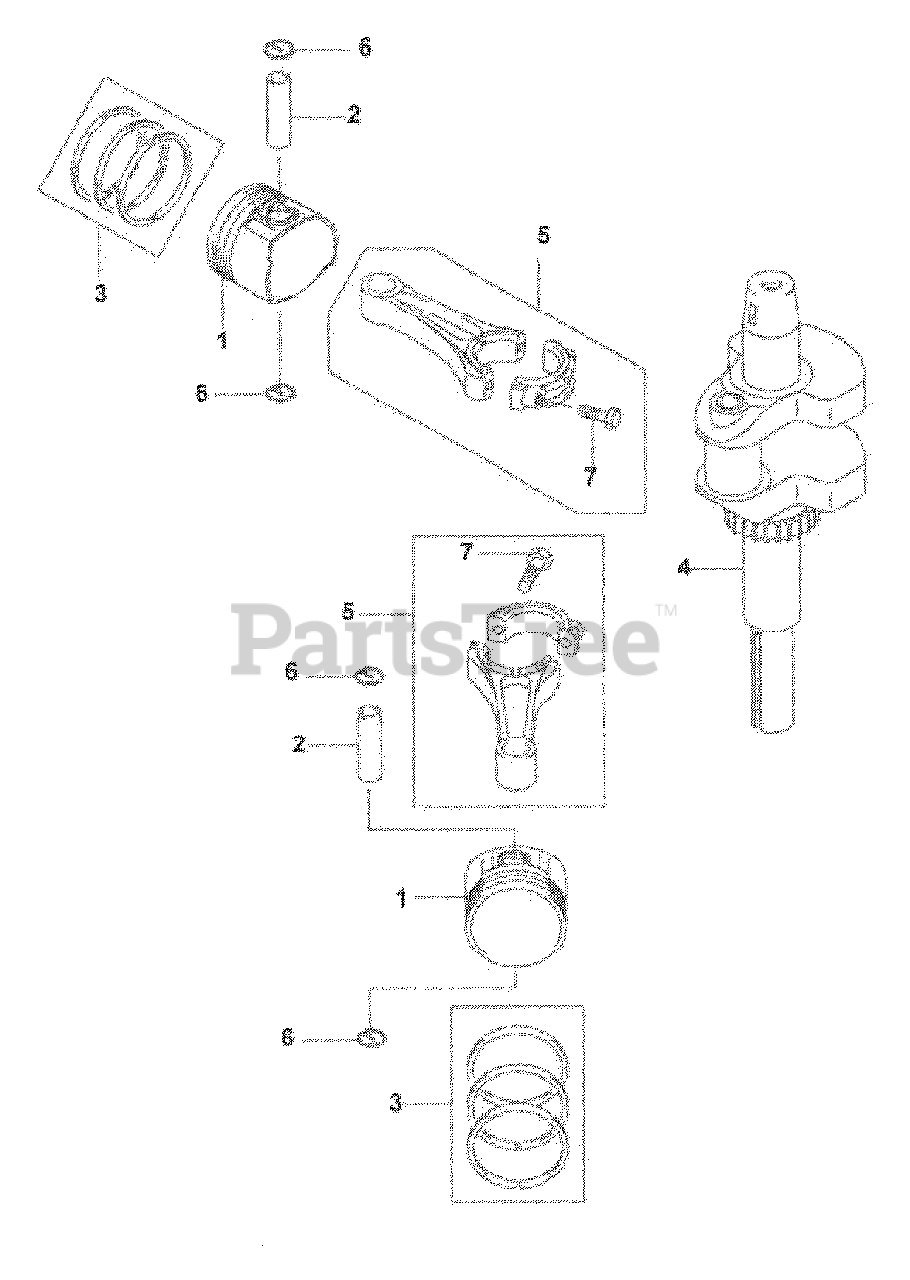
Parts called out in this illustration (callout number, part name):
3	Piston Ring Set
5	Connecting Rod
7	Flange Bolt
